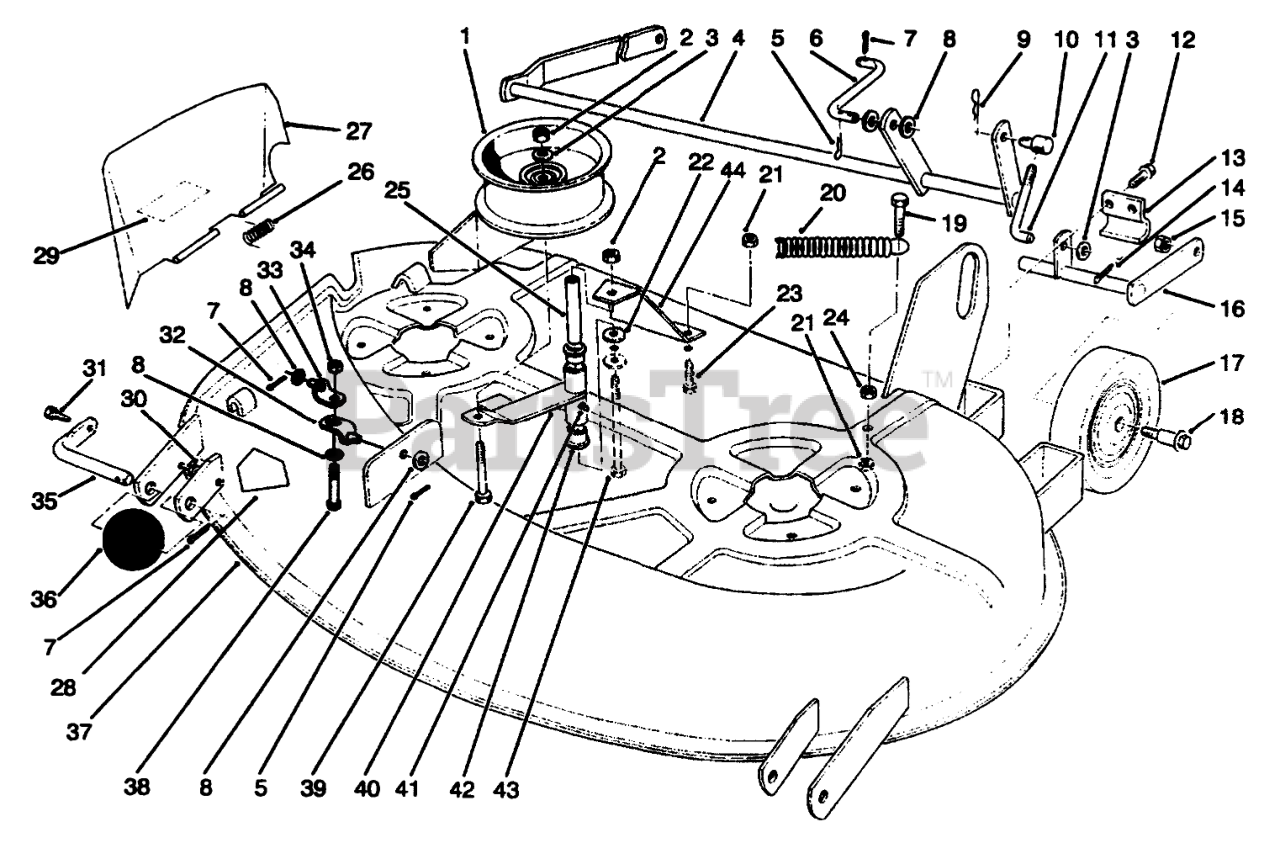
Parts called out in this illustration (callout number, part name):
1	Pulley-Idler
2	NUT-LOCK, NI
3	WASHER-FLAT
4	Shaft-R.H.
5	PIN-COTTER
6	LINK-REAR
7	PIN-COTTER, HAIR
8	WASHER-FLAT
9	Hairpin
10	TRUNNION
11	ROD-LIFT
12	Bolt
13	Camp
14	PIN-COTTER
15	Nut-Hex
16	Shaft-L.H.
17	WHEEL
18	BOLT-SHOULDER
19	SCREW-HH
20	SPRING-EXTENSION
21	NUT-LOCK, NI
22	WASHER
23	SCREW-HH
24	NUT-HEX
25	SPACER
26	SPRING-TORSION
27	DISCHARGE CHUTE/DECAL
28	DECAL-DANGER
29	DECAL-DANGER, THROWN OBJECT
30	NUT-LOCK, NI
31	SCREW-HH
32	BRACKET-LIFT, LOWER
33	BRACKET-LIFT, UPPER
34	NUT-JAM
35	SHAFT-ROLLER
36	ROLLER
37	38 DECK W/DECALS
38	SCREW-HH
39	SCREW-HH
40	Arm-Idler
41	FITTING-GREASE
42	BUSHING
43	SCREW-HH
44	Brace
